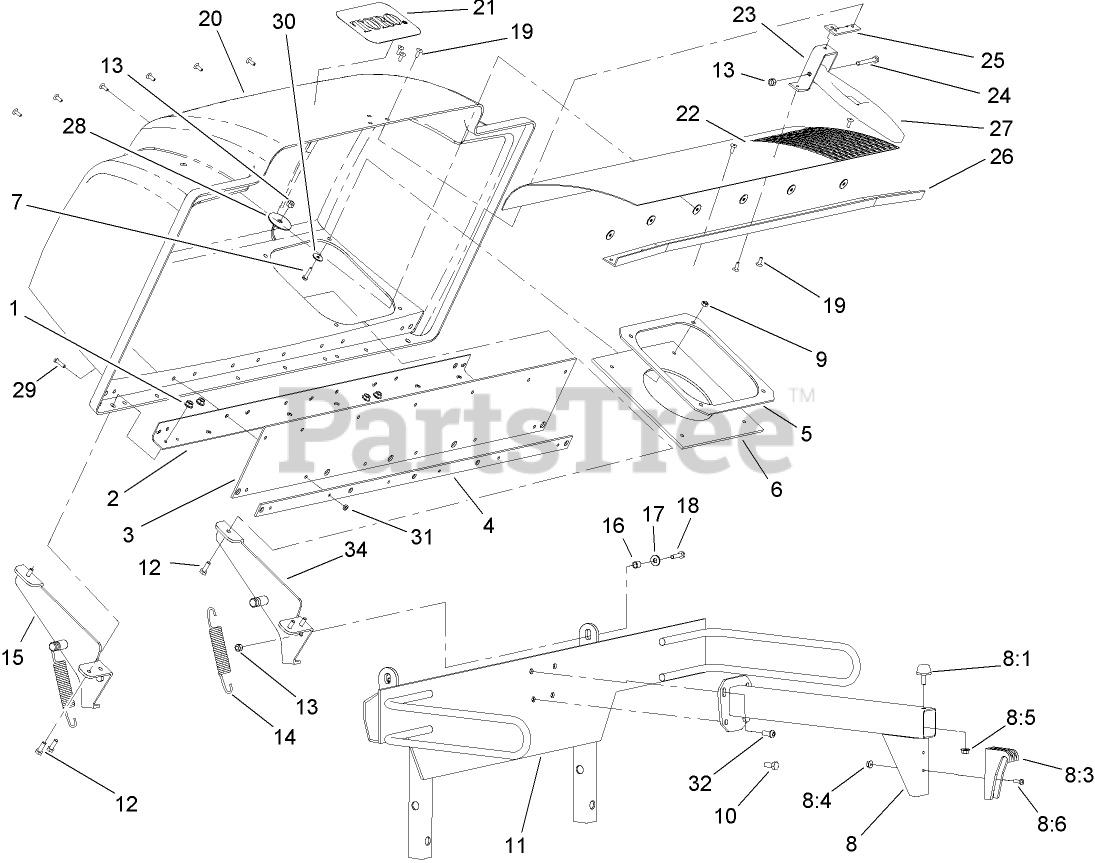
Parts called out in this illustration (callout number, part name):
1	NUT-HF
2	STIFFENER-BAGGER, TOP
3	SEAL-HOOD
4	PLATE-BACKING
5	CLAMP-SEAL
6	SEAL-CHUTE
7	SCREW-PPH
8	BAG SUPPORT ASM
8:1	BUMPER
8:4	NUT-HF
8:5	NUT-HF
8:6	SCREW-PPH
9	NUT-LOCK, NI
10	SCREW-HH
11	UPRIGHT-BAGGER
12	SCREW-HH
13	NUT-LOCK, NI
14	SPRING-EXTENSION
15	HINGE-RH
16	SPACER
17	WASHER-FLAT
18	SCREW-HH
19	RIVET-BLIND
20	HOOD ASM
22	SCREEN-BAGGER
23	ANCHOR-LATCH
24	SCREW-HH
25	REINFORCEMENT-LATCH
26	SUPPORT-SCREEN
28	WASHER
29	SCREW-HEAD, TRUSS
30	WASHER-FLAT
31	NUT-LOCK, SIDE
32	SCREW-HSBH
34	HINGE-LH
